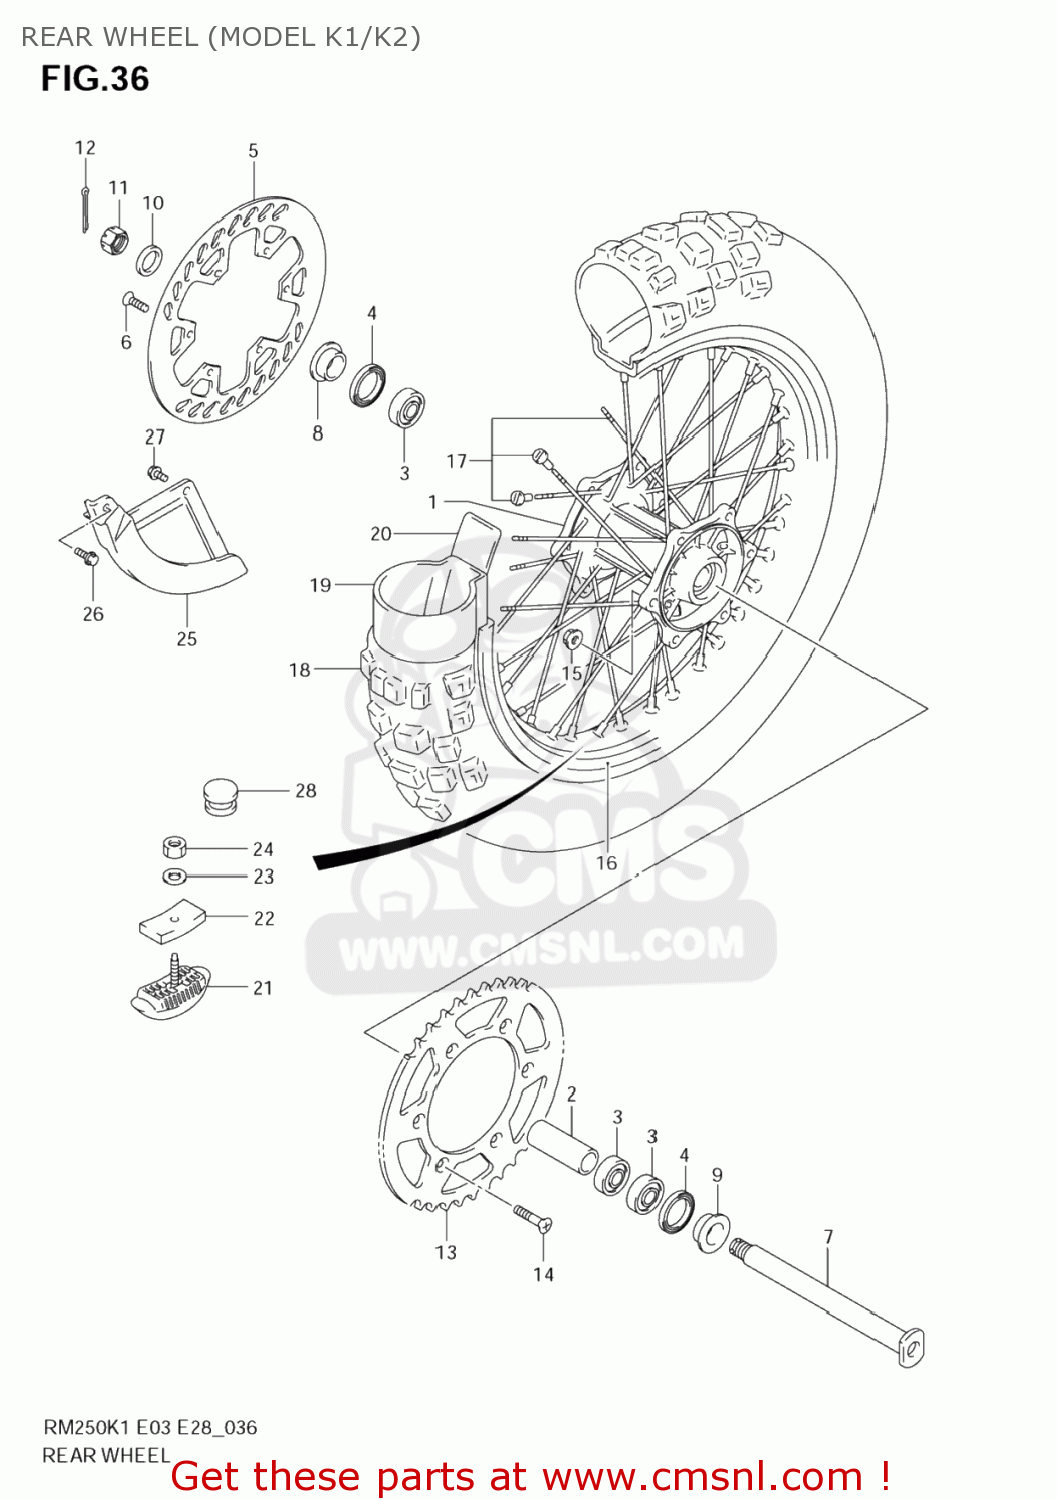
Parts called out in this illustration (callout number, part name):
1	HUB,RR WHEEL
2	SPACER,RR HUB BEARING
3	BEARING(22X44X12)
4	SEAL,OIL(30X44X7)
5	DISC,RR BRAKE
6	SCREW
7	AXLE,RR
8	SPACER,RR AXLE
9	SPACER,RR AXLE
10	WASHER(19X32X3.2)
11	NUT
12	PIN,COTTER
13	SPROCKET,RR(NT:49)
14	BOLT(8X30.5)
15	NUT
16	RIM,RR WHEEL(2.15X19 AL.)
17	SPOKE SET,RR WHEEL
18	TIRE,REAR 110/90-19
19	TUBE ASSY,WHEEL INNER
20	PROTECTOR,WHL INR TUBE
21	STOPPER,BEAD(2.15)
22	CUSHION,BEAD STOPPER
23	WASHER
24	NUT
25	COVER,REAR DISC
26	BOLT
27	BOLT
28	CAP(OD:12)
